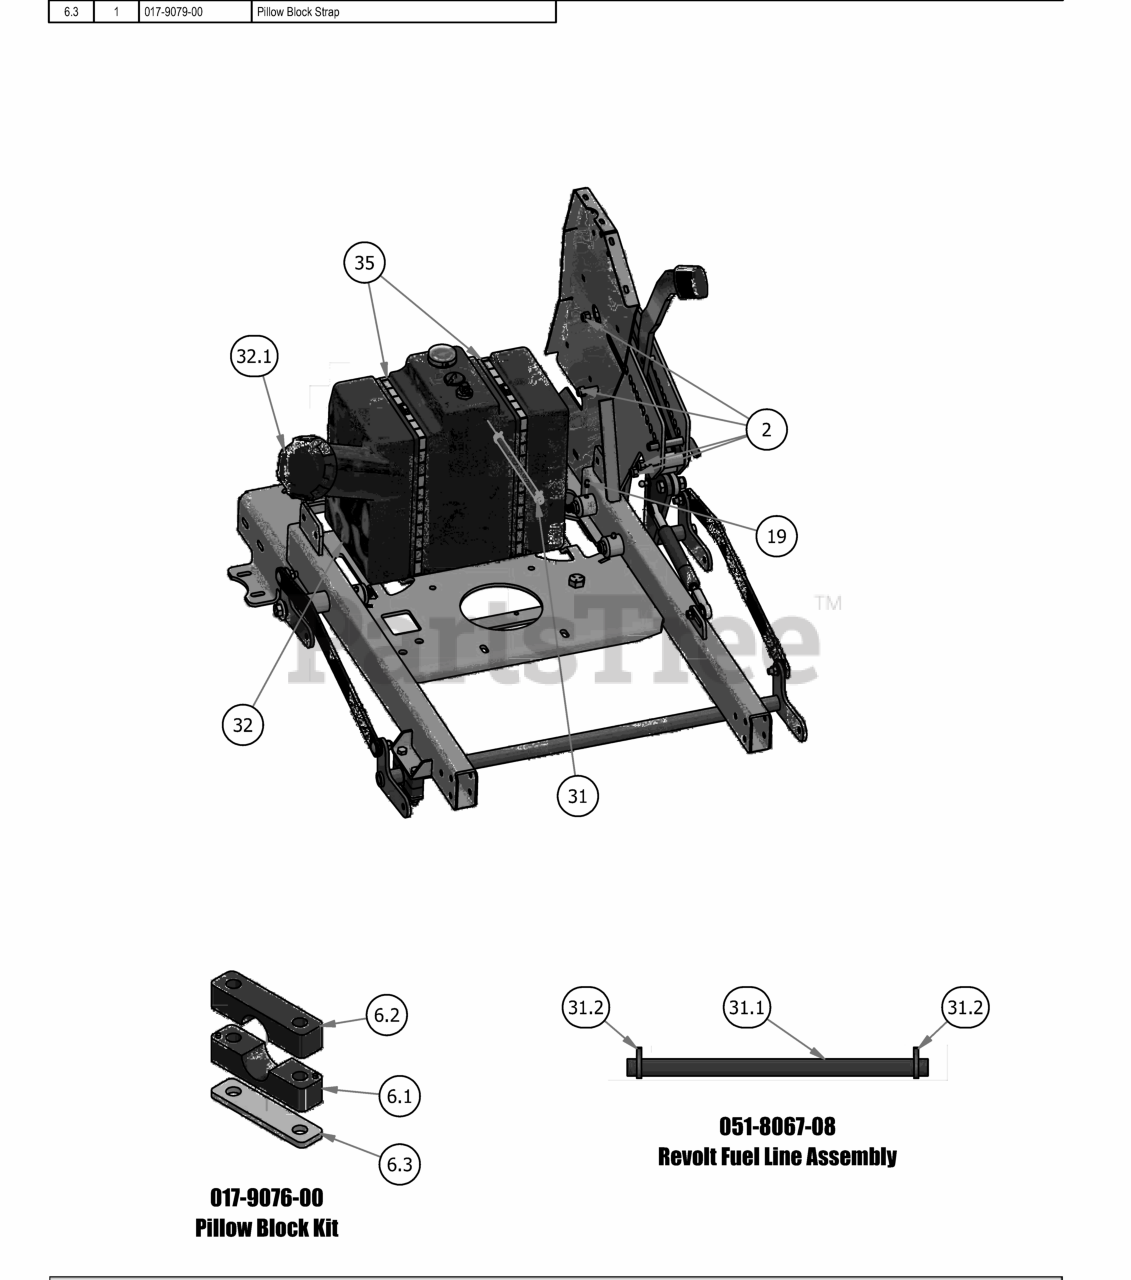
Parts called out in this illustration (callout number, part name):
2	3/8 Nylock Nut
6.1	Pillow Block MZ male
6.2	Pillow Block MZ female
6.3	Pillow Block Strap
19	1/4" Press in Grease Fitting
31	Revolt Fuel Line Assembly
31.1	1/4 Fuel Line
31.2	1/4 Fuel Hose Clamp
32	2019 REVOLT FUEL TANK
35	2019 Stand On Gas Tank Strap
